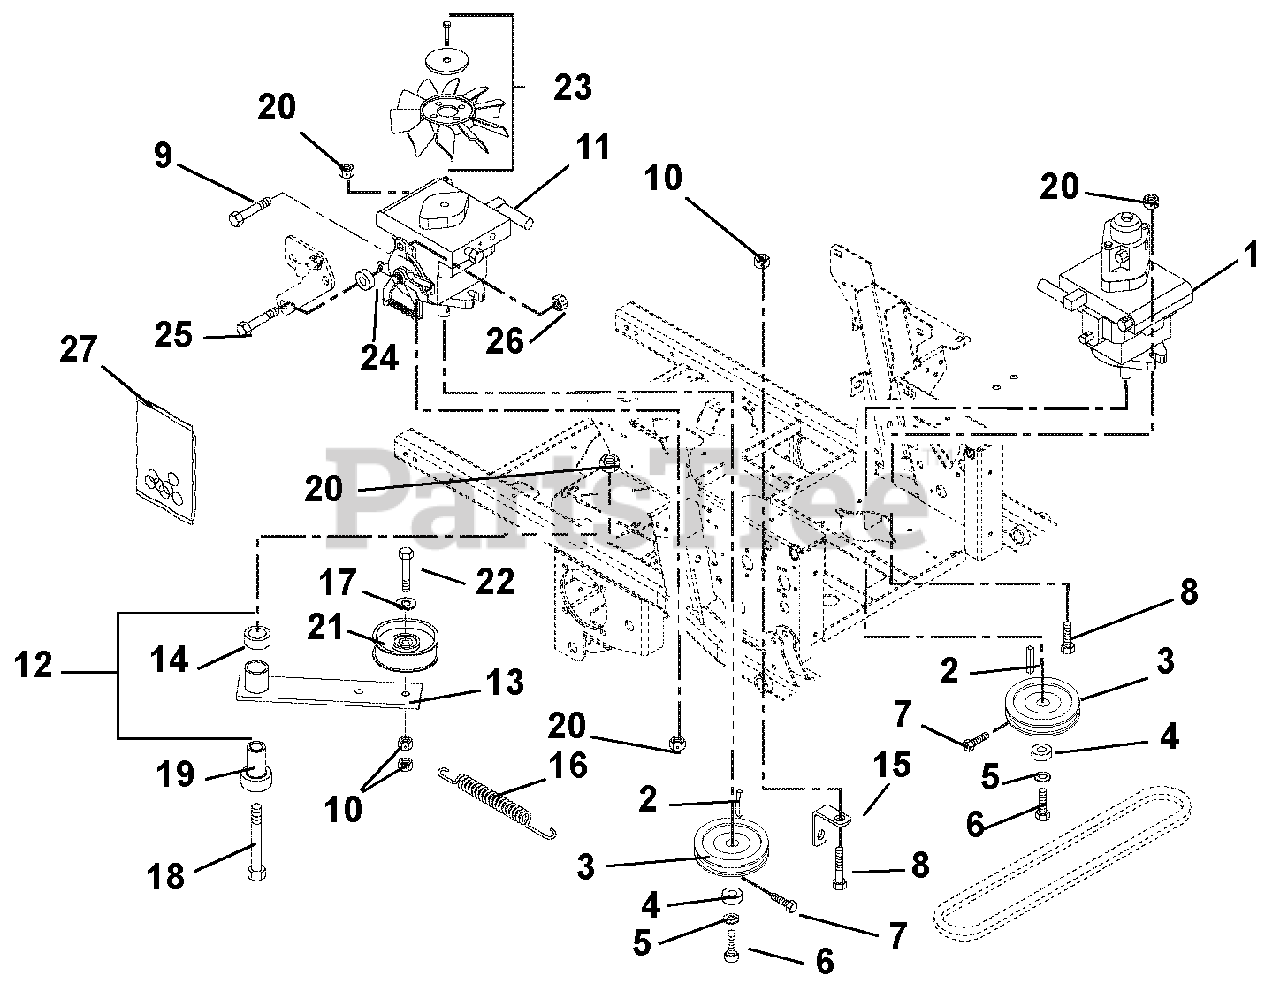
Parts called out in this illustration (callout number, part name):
1	Pump, Hydraulic with Auxiliary
2	Key, Square 5 x 5 x 30mm Plain
3	Sheave, Poly V .671 x 4.125
4	Washer, Flat Steel .281 x 1.000 x .063
5	Washer, Locking .25 x .062
6	Bolt, Hex M6 x 1.0 x 12 YZ EP30
7	Screw, Socket Head .25-20 x .50 EP80
8	Bolt, Hex .50-13 x 1.50 Grade 5
9	Bolt, Hex .31-18 x .75 Grade 5
10	Nut, Locking Top Flange .38-16
11	Pump, Hydraulic BDP-21 with Thru Fan
12	Assembly, Idler Arm Guard Drive
13	Weldment, Idler Arm Ground Drive
14	Bushing, 1.00 x 1.125 x 1.936
15	Anchor, Spring Idler
16	Spring, Extension
17	Washer, Flat Steel .39 x .75 x.125
18	Bolt, Hex .50-13 x 3.50 Grade 5
19	Bearing, Pedestal
20	Nut, Locking Top Flange .50-13
21	Idler, Flay 4.00 x .38
22	Bolt, Hex .38-16 x 2.25 Grade 5
23	Fan, Hydro Pump Cooling
24	Spacer .318 x .43 x .375
25	Bolt, Hex .31-18 x 1.25 Grade 5
26	Nut, Locking Top Flange .31-18
27	Kit, Pump Seal (BDP-21A)
